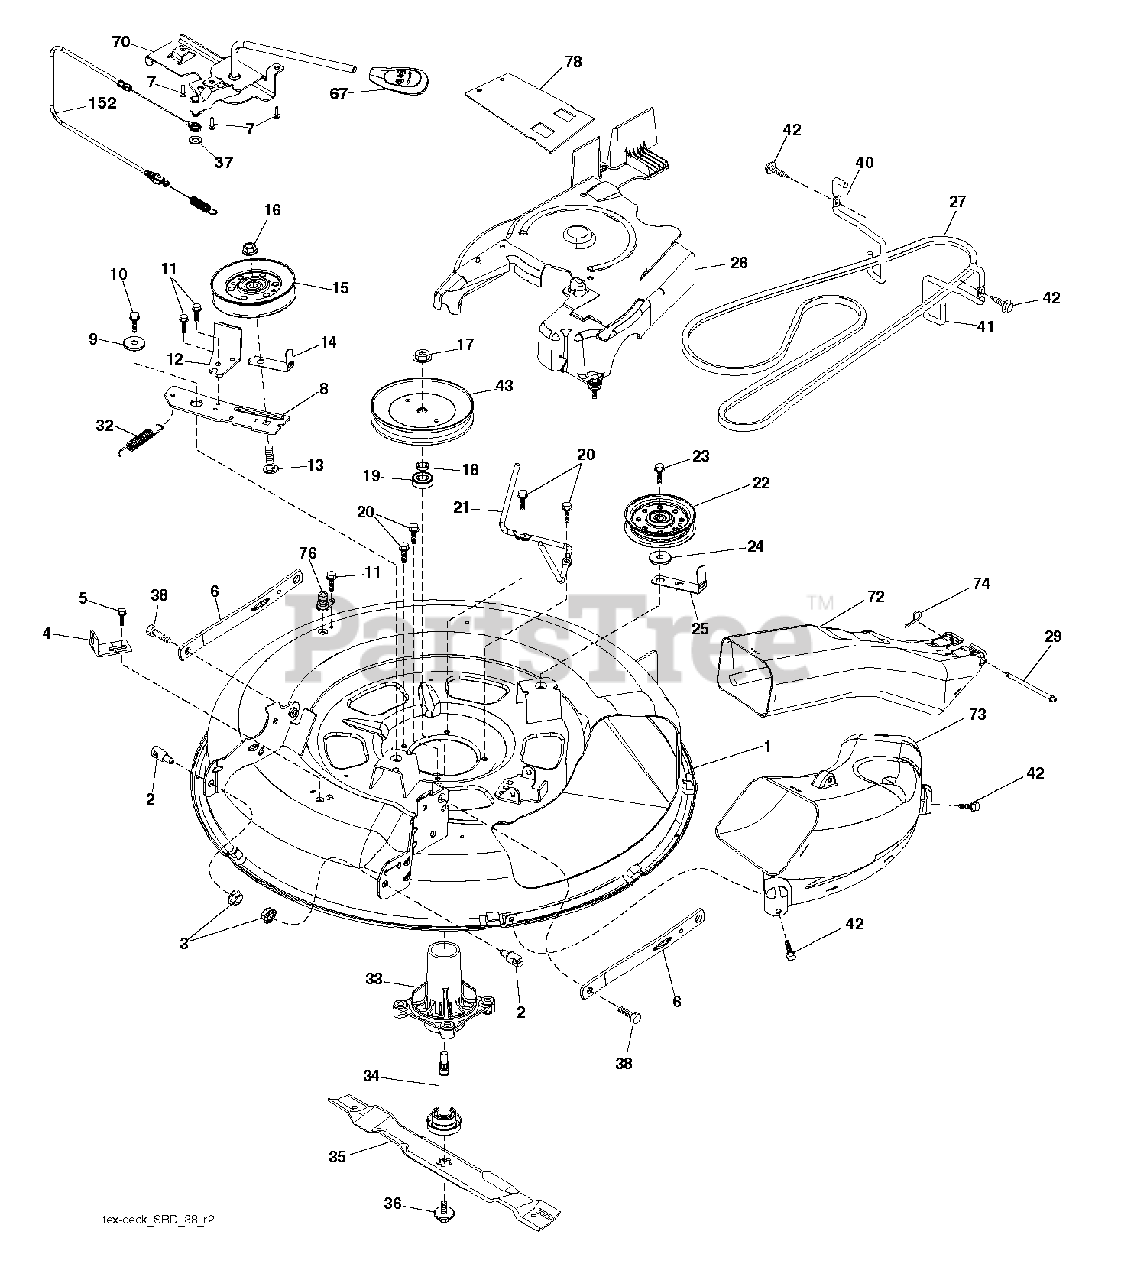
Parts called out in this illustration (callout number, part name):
1	DECK.WELDMENT.PNT.30"SRD
2	STUD.FASTNER.W/ANTI-ROTATE
3	NUT LOCK HEX FLANGE 5/16-18
4	BRACKET.CLUTCH.CABLE
5	BOLT.5/16HEX.WHS.HD
6	ARMS.SUSP.MOWER.REAR.SRD
7	SCREW.#10 X 0.750.BOS
8	ARM.IDLER.30"SRD
9	SPACER.RETAINER
10	SCREW 3/8-16X1
11	SCREW.1/4-20X5/8
12	RP ARM.BRAKE.MOWER.38"LH.TEX
13	BOLT.3/8-16X1.50
14	KEEPER, BELT IDLER
15	PULLEY.IDLER.4.25
16	NUT LOCK FLG 3/8-16 UNC
17	NUT.FLANGE.LOCK.TOP
18	WASHER.SPACER.MANDREL
20	SCREW, WASHER HEAD
21	KEEPER.BELT.MANDREL.30"
22	PULLEY.IDLER.FLAT.46.PR.DR.
23	SCREW LT
24	WASHER
25	KEEPER.BELT.30"SRD
26	COVER.ASM.MANDREL.30"
27	V-BELT.DRIVE.MOWER.30"
29	PIN.HINGE.30".SRD
32	SPRING RETURN
33	HOUSING.MANDREL.4PT.
34	SHAFT.ASM.MDRL.N/GREASE.38
35	BLADE.MOWER.BAGGING.30"
36	BOLT.WASHER.ASM.7/16-2
37	WASHER
38	BOLT.SHOULDER
40	KEEPER.BELT.ENGINE.LH.LT.SRD
41	KEEPER.BELT.ENGINE.RH.LT.SRD
42	SCREW, 3/8-16X3/4
43	PULLEY, MANDREL 6.5 PD
67	HANDLE.CLUTCH.CABLE.LT
70	CLUTCH.ASM.MANUAL.LT.PRED
72	CHUTE.UPPER.SRD.30R"
73	CHUTE.LOWER.SRD.30R"
74	Retainer Spring
76	PORT.WASHOUT
78	GUARD ARM CLUTCH
152	CABLE.CLUTCH.MANUAL.
